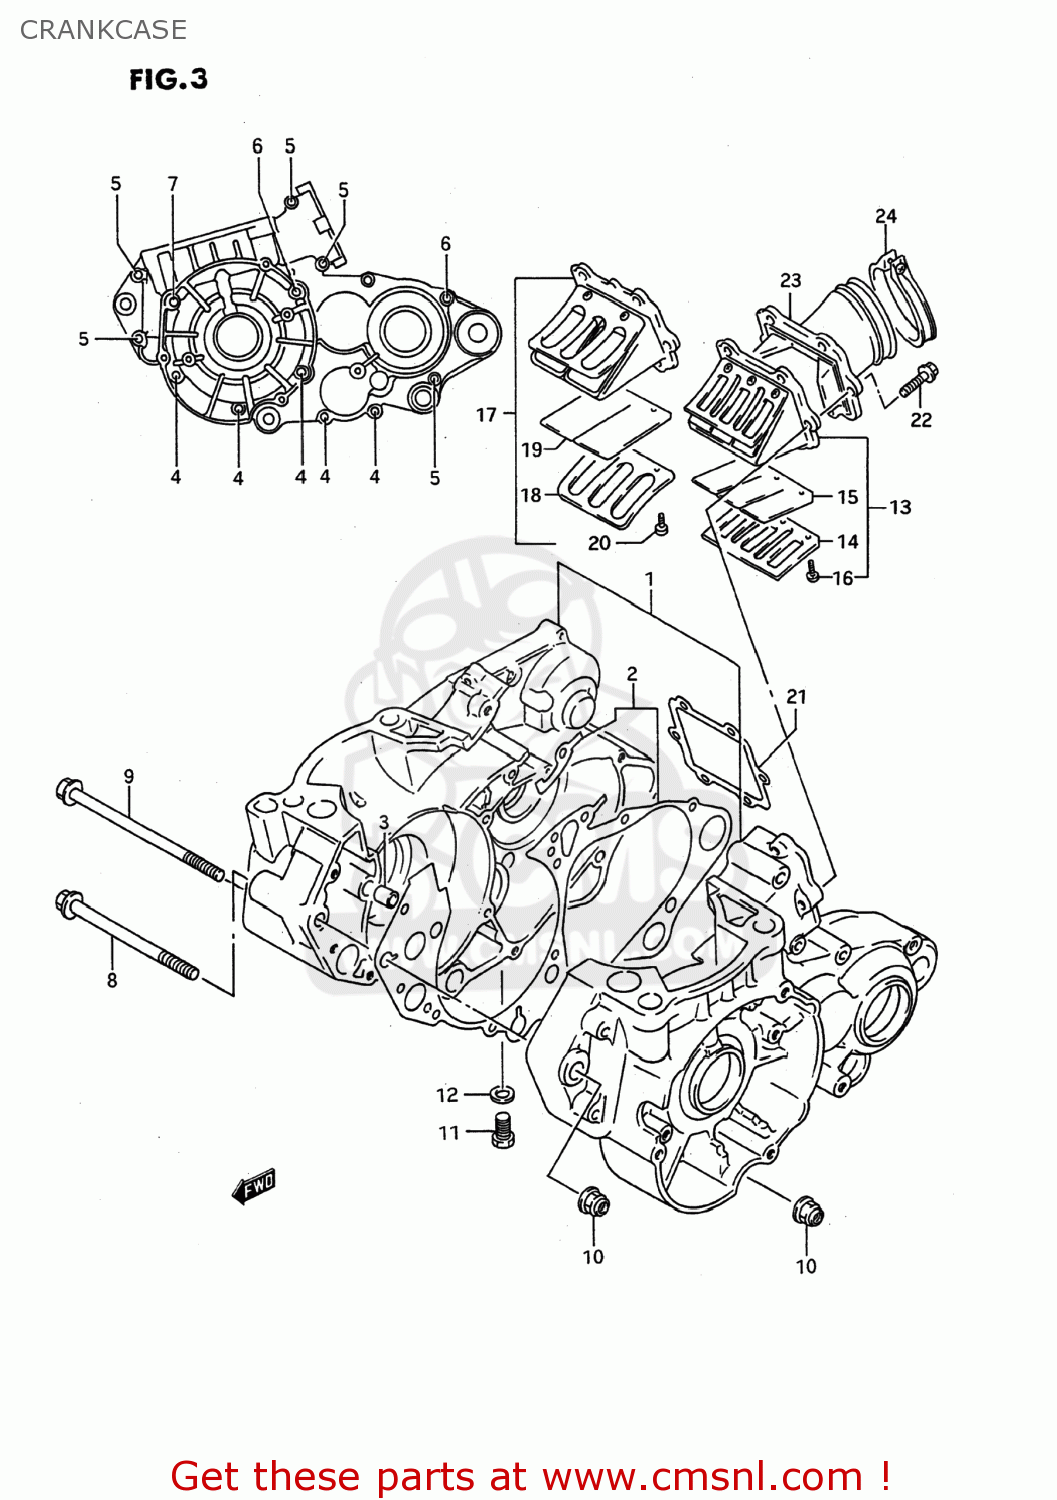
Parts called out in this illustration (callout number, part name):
1	CRANKCASE SET
2	GASKET,CRANKCASE (NAS)
3	PIN
4	BOLT
5	BOLT
6	BOLT
7	BOLT
8	BOLT
9	BOLT
10	NUT
11	BOLT
12	GASKET(8.2X14X1) (NAS)
13	VALVE ASSEMBLY,REED
14	STOPPER,REED VALVE
15	VALVE,REED
16	SCREW
17	VALVE ASSY,REED
18	STOPPER,REED VALVE
19	VALVE,REED
20	SCREW
21	GASKET,REED VALVE (NAS)
22	BOLT
23	PIPE,INTAKE
24	CLAMP
